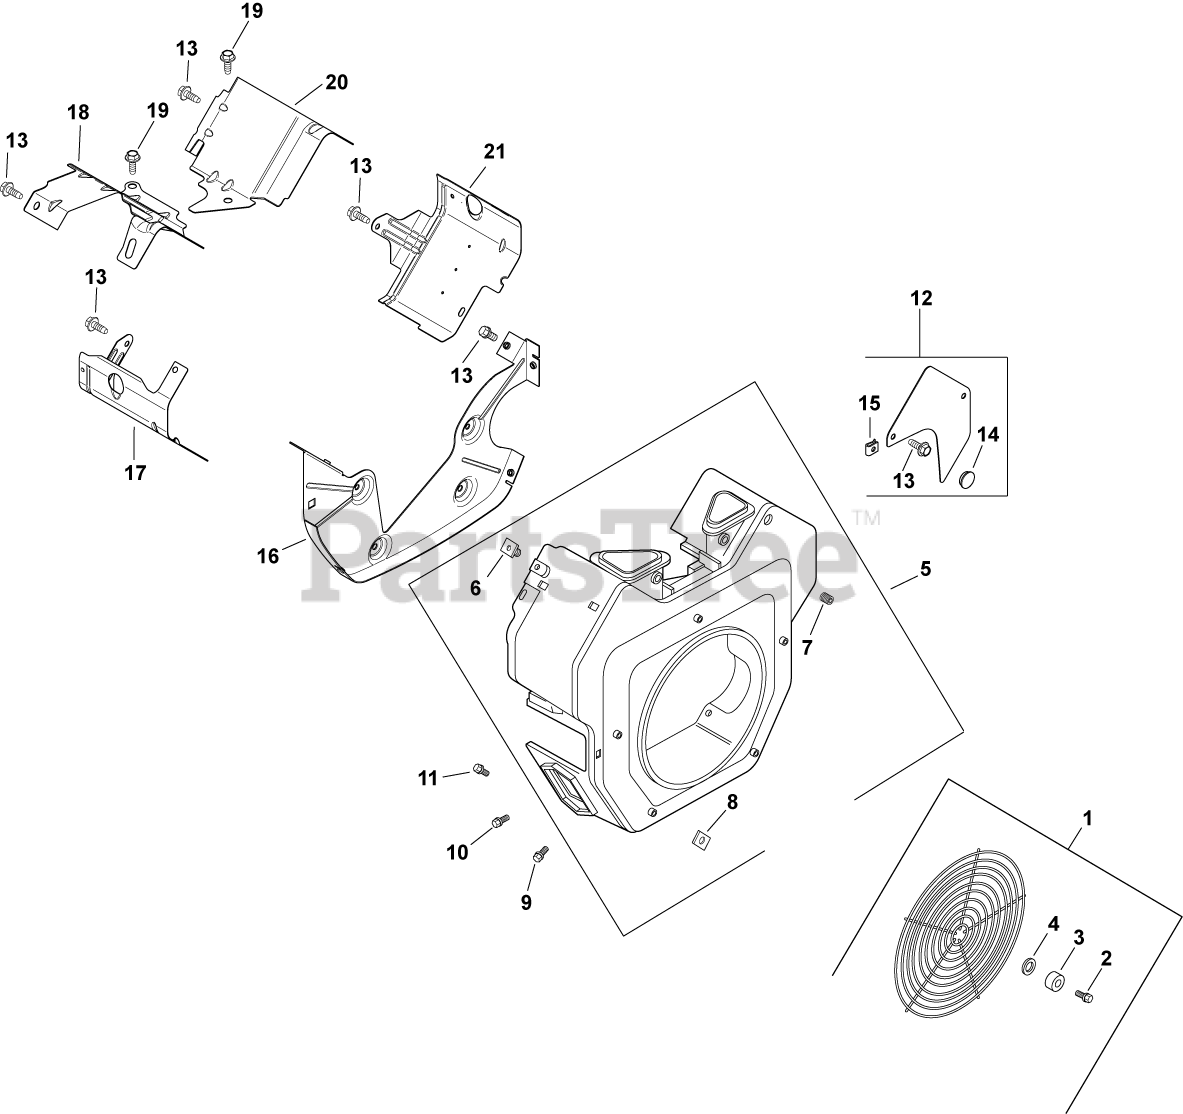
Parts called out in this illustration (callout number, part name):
1	KIT, GUARD
2	SCREW, PAN HEAD-USE 25 086 160-S
3	SPACER USE 25 112 30-S
4	WASHER, FLAT 7/32"
5	KIT, BLOWER HOUSING ASSEMBLY
6	NUT, PLASTIC
7	SCREW, SKT SET #10-24X1/4"
8	NUT, PLASTIC (KM)-USE 25 100 37-S
9	SCREW, FLG THD FRM M5X.8X20-(#25086399S)
10	SCREW,FLG THD FRM M5X0.8X16-(#25086398S)
11	SCREW - USE M-545016-S
12	KIT, ACCESS PANEL
13	SCREW,FLG THD FRM M6X1.0X16-(#25086397S)
14	PLUG, BUTTON 9/16
15	CLIP, MOUNTING-USE 25 154 13-S
16	PLATE, BACKING-USE 24 146 59-S
17	BAFFLE,VALLEY #2SIDE(KM)-USE 24 063 88-S
18	BAFFLE, VALLEY #2 SIDE-USE 24 063 94-S
19	SCREW, FLG THD FRM M5X.8X10
20	BAFFLE, VALLEY (CH)-USE 24 063 93-S
21	BAFFLE, RIGHT BARREL-USE 24 063 85-S
